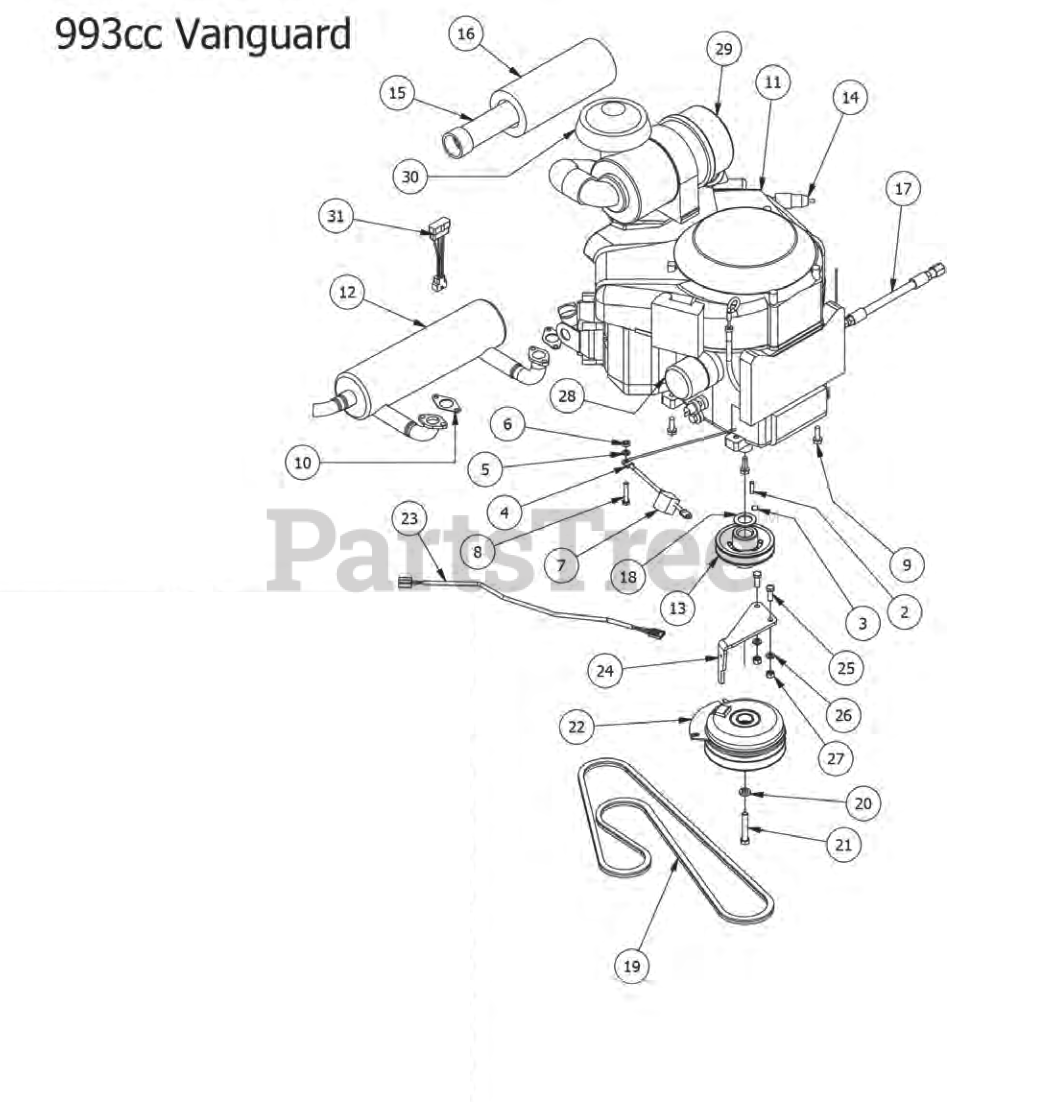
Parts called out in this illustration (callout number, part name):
2	1/4" x 1" Key
3	5/16 Set Screw
4	Starter to chassis cable
5	5/16" Lock Washer
7	Black Boot For ground cable
8	5/16" x 1 3/4" Hex Bolt
9	3/8 x 1 1/8 bolt
10	Exhaust Gasket for 23 Vanguard
11	993cc Briggs Vanguard Engine
12	32Hp Vanguard Exhaust
13	4 3/4 Motor Pulley
14	Universal inline Fuel Filter
15	Canister Air Filter- Inner
16	Canister Air Filter- Outer
17	14 mm Oil drain Hose 993cc Vanguard
18	1 1/8" Flat Spacer
20	7/16" Lock Washer
21	7/16" x 2 1/2" Hex Bolt
22	Clutch Assembly
23	Clutch Pigtail
24	PTO Engager Holder
25	3/8" x 1" Hex Bolt
26	3/8" Lock Washer
27	3/8" Hex Nut
28	Briggs Oil Filter
29	Complete Canister
30	Rain Cap Fits all Canisters
31	Harness Adaptor - 933cc Vanguard
